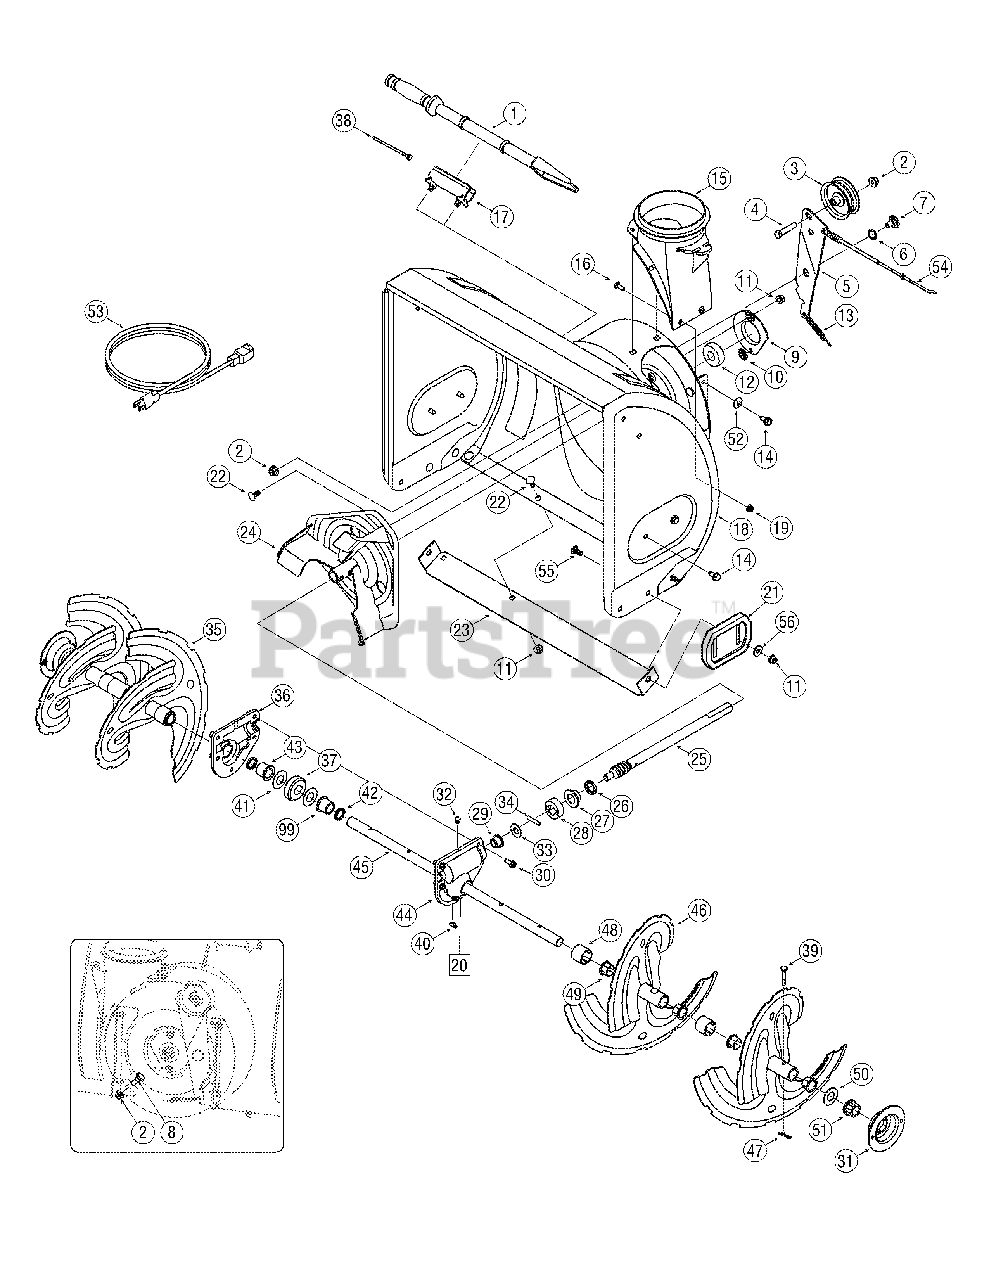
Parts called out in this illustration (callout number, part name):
1	Clean-Out Tool
2	Flange Lock Nut
3	Flat Idler Pulley
4	Hex Bolt, 3/8-16 x 1.75
5	Auger Idler Bracket
6	Wave Washer
7	Shoulder Screw
8	Shoulder Screw
9	Bearing Housing
10	Push Nut
11	Flange Lock Nut, 5/16-18
12	Ball Bearing
13	Extension Spring
14	Screw, 5/16-18 x 0.750
15	Chute Adapter
16	Carriage Screw, 1/4-20 x 0.75
17	Clean-out Tool Mtg. Bracket
18	Auger Housing Assembly, 26-inch
19	Flange Lock Nut, 1/4-20
20	Gearbox Assembly, 26-inch
21	Slide Shoe
21	Standard Polymer Reversible Shoe Kit
22	Carriage Bolt
23	Shave Plate
24	Impeller Assembly
25	Worm Shaft
26	Oil Seal
27	Flange Bearing
28	Thrust Collar
29	Flange Bearing
30	Screw, 1/4-20 x 0.75
31	Bearing Housing
33	Flat Washer
34	Dowel Pin
35	Spiral Assembly-RH
36	Reducer Hsg.-RH
37	Worm Gear, 20T
38	Cable Tie
39	Shear Pin
40	Key
41	Flat Washer
42	Oil Seal
43	Flange Bearing
44	Reducer Hsg.-LH
45	Axle, Auger, 26"
46	Spiral Assembly-LH
47	Bow Tie Cotter Pin
48	Spacer
49	Flange Bushing
50	Flat Washer
51	Hex Flange Bearing
52	Bell Washer
53	Extension Cord
54	Auger Clutch Cable
55	Screw, Carriage, 5/16-18 x 1.00
56	Washer, Flat, .349 x .879 x .063
